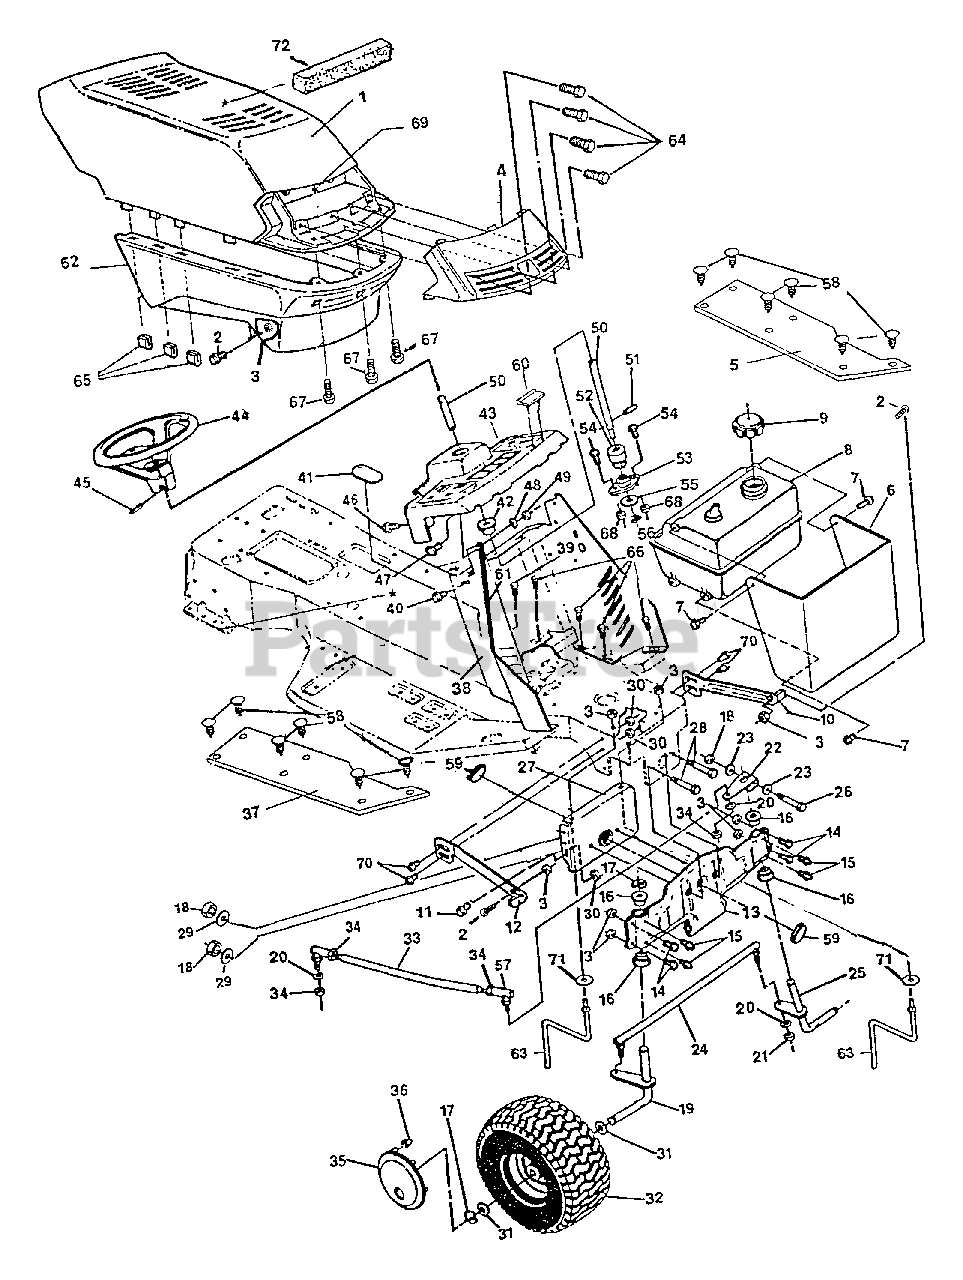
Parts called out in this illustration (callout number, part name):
2	Shoulder Bolt, 5/16-18 Thd.
3	Nut, Hx, Ctrlk, 5/16-18 Thd.
4	Lens, Headlight
5	Assembly, Foot Pad L. H.
6	Heat Shield
7	Screw, Hx Hd, Plastite 1/4 Dia x 3/4 In
8	Tank, Gas 1.5 Gal W/Sensor
8	Low Fuel Sensor
10	Bracket, Hood L. H.
11	Screw, Hx Hd, 5/16 -18 x 3/4 In.
12	Bracket, Hood R. H.
13	Front Axle W/Bearings
14	Screw, Hx Hd, 5/16-18 x 5/8 In.
15	Grease Fitting
16	Bearing, Spindle
18	Nut, Hx, Ctrlk, 3/8-16 Thd.
19	Spindle, R. H.
20	Washer, Split, Lock 3/8 In.
21	Nut, Hx, 3/8-24 Thd.
22	Steering Arm, Upper
23	Washer, Flat, 25/64 In.
24	Assembly, Tie Rod
25	Spindle, L.H.
26	Screw, Hx Hd, 3/8-16 x 2-1/2 In.
27	Support Bracket, Front Axle
28	Screw, Hx Hd, 3/8-16 x 3 In.
29	Washer, Spring
30	Nut, Hx, Wd Fl Lk 5/16-18 Thd.
31	Washer, Flat, 3/4 In.
32	Wheel & Tire Assembly, Front Tire
32	Wheel/With Bearing
32	Valve Stem
34	Nut, Hx, Jam, 3/8-24 Thd.
35	Hubcap, Front
36	Clip, Hubcap
37	Assembly, Foot Pad R. H.
38	Dash, Lower
39	Screw, Tap, 5/16-18 x 3/8 In.
40	Screw, Self-Tap, 1/4-20 x 1/2 In.
42	Bushing, Upper Steering
43	Dash, Upper
44	Steering Wheel
45	Pin, Spring, 1/4 x 2 In.
46	Screw, Tap, 1/4-20 x 1/2 In.
47	Screw, Hx Hd, 1/4-20 x 5/8 In.
48	Washer, Flat, 9/32 In.
49	Nut, Hx, Ctrlk, 1/4-20 Thd.
50	Shaft, Steering
51	Pin, Dowel
52	Pinion, Steering
53	Bearing, Flange
54	Screw, 5/16-24x .75 Sq.
55	Washer, Flat, 1/2 In.
57	Ball, Joint, 3/8 Thd.
58	Ratchet Fastener
59	Plug, Front Axle
60	Bumper, Hood/Dash
61	Wide Trim 18"
63	Belt Guide
64	Screw, #4-24 x 1/2 In.
65	Clip, Tinnerman
66	Screw, 5/16-18 x 50 In.
67	Screw, #10 x 1/2 In.
68	Nut, 5/16-24 Hxwdfllk
69	Decal, Reflector Ver II, Hood
70	Screw, Hex Fl, 5/16-18 x 3/4 In.
71	Washer, Internal Tooth
72	Foam, Hood Baffle
